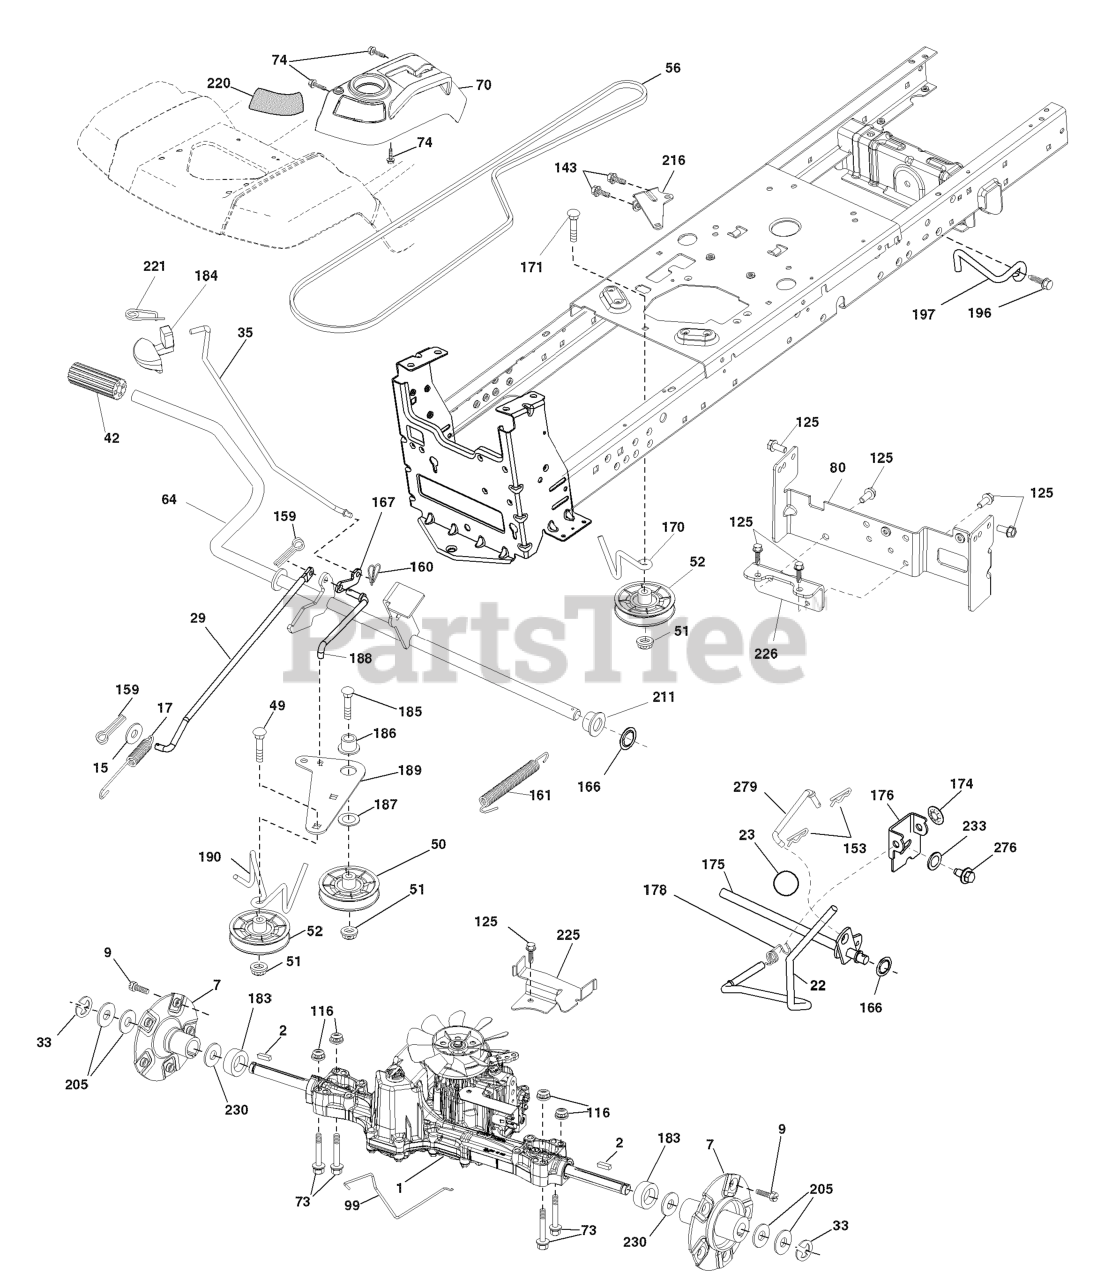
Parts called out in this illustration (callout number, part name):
1	TRANSAXLE.K66.AD.FCH.TG
2	KEY 1/4 X 2.5
7	HUB.ASM.WHEEL.REAR.23"TEX
9	HUB BOLT
15	WASHER
17	SPRING.BRAKE.K46
22	ROD.SHIFT.FENDER.STGT.
23	KNOB.DELUXE.(PISTOL.GRIP).BLAC
29	ROD.BRAKE.K66
33	E RING HYT
35	ROD.BRAKE.PARKING.GT.H
42	PEDAL COVER T
50	IDLER.FLAT.910.OFFSET
51	NUT LOCK FLG 3/8-16 UNC
52	IDLER.V-GROOVE.910.OFFSET
64	SHAFT.ASM.PEDAL.BRAKE.
70	RP CONSOLE.ASM.HYDO.HUSQ.
73	BOLT HEX 5/16-18 GR 5
74	SCREW.HI-LO.CONSOLE
80	STRAP.TORQUE.K66
99	ROD.SPRING.BYPASS.K66.GT.Z
116	NUT LOCK HEX FLANGE 5/16-18
125	SCREW
143	Screw Thdrol 5/16-18 x 1/2
153	RETAINER M
159	COTTER PIN
160	RETAINER CLIP
161	SPRING, RETURN LT
166	NUT.PUSH.625.2006
167	LATCH.BRAKE.SPRING
170	KEEPER.V-IDLER.CENTER.
171	BOLT
174	NUT.PUSH.500.2006
175	SHAFT.ASM.SHFT.T2.TLT
176	ARM.CLEVIS.ROD.SHIFT
178	SPRING.SHIFT.GT2006
183	SPACER.AXLE.HG.TEX
184	HANDLE.PARKG.BRK.HUSQ X667
185	BOLT
186	SPACER.RETAINER
187	WASHER 12/32X2X10GA
188	RP.LINK.CLUTCH.GROUND.DRIVE
189	BELLCRANK.GROUND.DRIVE.TEX.
190	KEEPER.BELLCRANK.DRIVE
195	RETAINER.ROD.BRAKE.HG3000.TEX
196	SCREW 3/8-16X1
197	BRKT.ANIT-ROTATION.CLUTCH
211	BUSHING.SHAFT.BRAKE.HAND
216	BRACKET.PULLEY.IDLER.W/TEX
220	REFLECTOR.RH.TEX GT
221	RETAINER.SPRING.CLIP.H
225	KEEPER.BELT.TRANSAXLE.K66
226	BRACKET.MOUNT.TORQUE.K66.TG
233	WASHER SERRATED
276	BOLT FIN HEX 7/16-14 X 1
279	LINK.ASM.SHIFT.FENDER.K66
